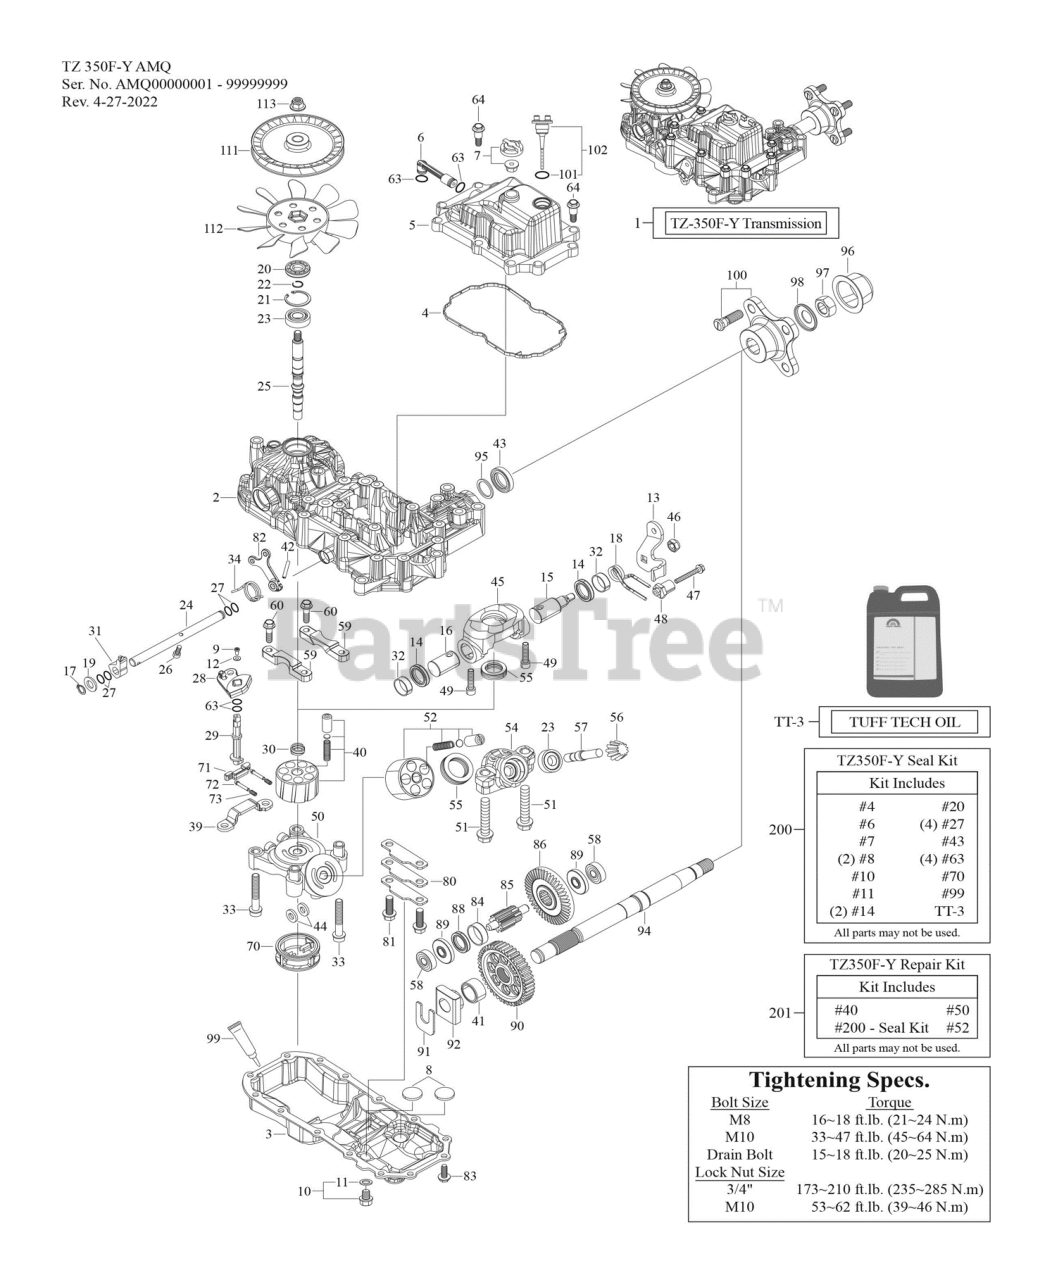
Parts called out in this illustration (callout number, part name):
1	HYDRO TRANSMISSION (RH)
2	UPPER HOUSING Y
3	LOWER HOUSING
6	BYPASS PIPING
7	VALVE ASSEMBLY-VENT
10	DRAIN BOLT KIT
11	WASHER-SEAL DRAIN BOLT
12	WASHER 4.5X10X1
13	CONTROL LEVER Y
15	CONTROL SHAFT
16	CONTROL SHAFT SHORT
18	TORSION SPRING
19	FLAT WASHER 12
20	SEAL-OIL 15X35X07
23	BALL BEARING
26	SOCKET BOLT 6X16
30	SPRING-CYL BLOCK
31	BRAKE FORK 20 CR
32	CONTROL BUSH LFB2510
33	HEX BOLT M10X65
34	SPRING, BRAKE YA
39	CHECK STOPPER PFG
40	CYLINDER BLOCK KIT
42	SPRING PIN 5 x 3
43	SEAL TC284008
50	CENTER CASE
52	BLOCK KIT-PISTON & MOTOR
54	MOTOR HOUSING
55	THRUST BEARING
58	BEARING 6201 CN
59	REDUCTION PLATE
60	FLANGE BOLT 8X30
64	TAPPING BOLT 8X30
73	BYPASS SPRING
83	TAP SCREWPING
84	FINAL PINION COLLAR
85	FINAL PINION SHAFT
86	REDUCTION GEAR
88	REDUCTION COLLAR
89	WASHER 14.1X30X3.5
97	LOCK NUT 3/4-16
98	FLANGE SPACER
113	NUT-LOCK PMP SHAFT
200	SEAL KIT (INCLUDES OIL)
201	REPAIR KIT (INCLUDES OIL)
202	OIL CHANGE KIT (TZ-350)
TT-3	TUFF TECH OIL 3 LITER BOTTLE
